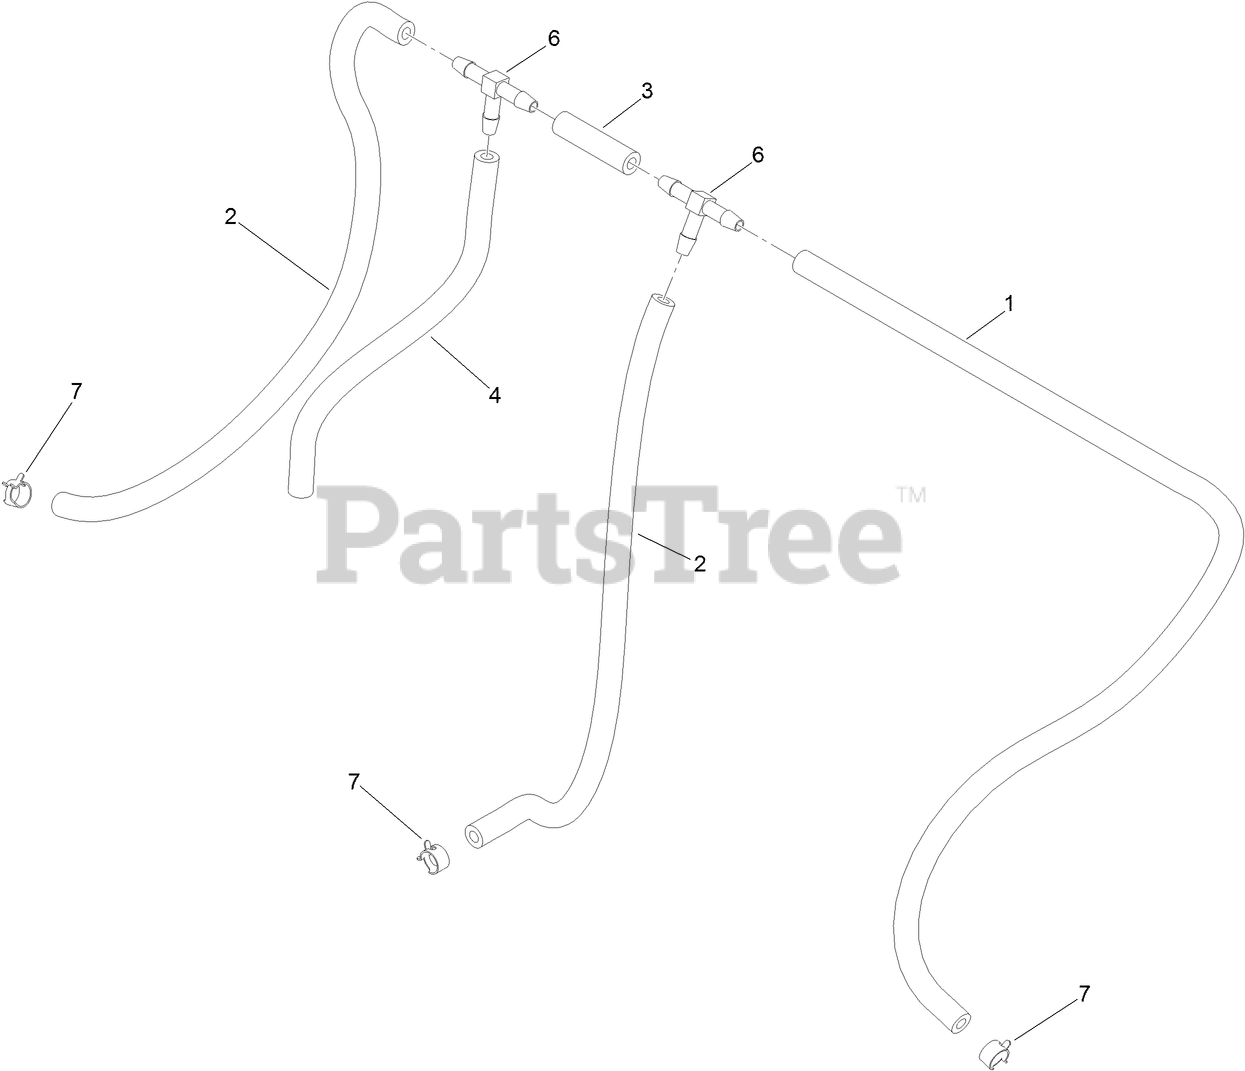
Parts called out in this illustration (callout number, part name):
1	HOSE-FUEL
2	HOSE-FUEL
3	HOSE-FUEL
4	HOSE-FUEL
6	FITTING-TEE, BARBED
7	CLAMP-HOSE
